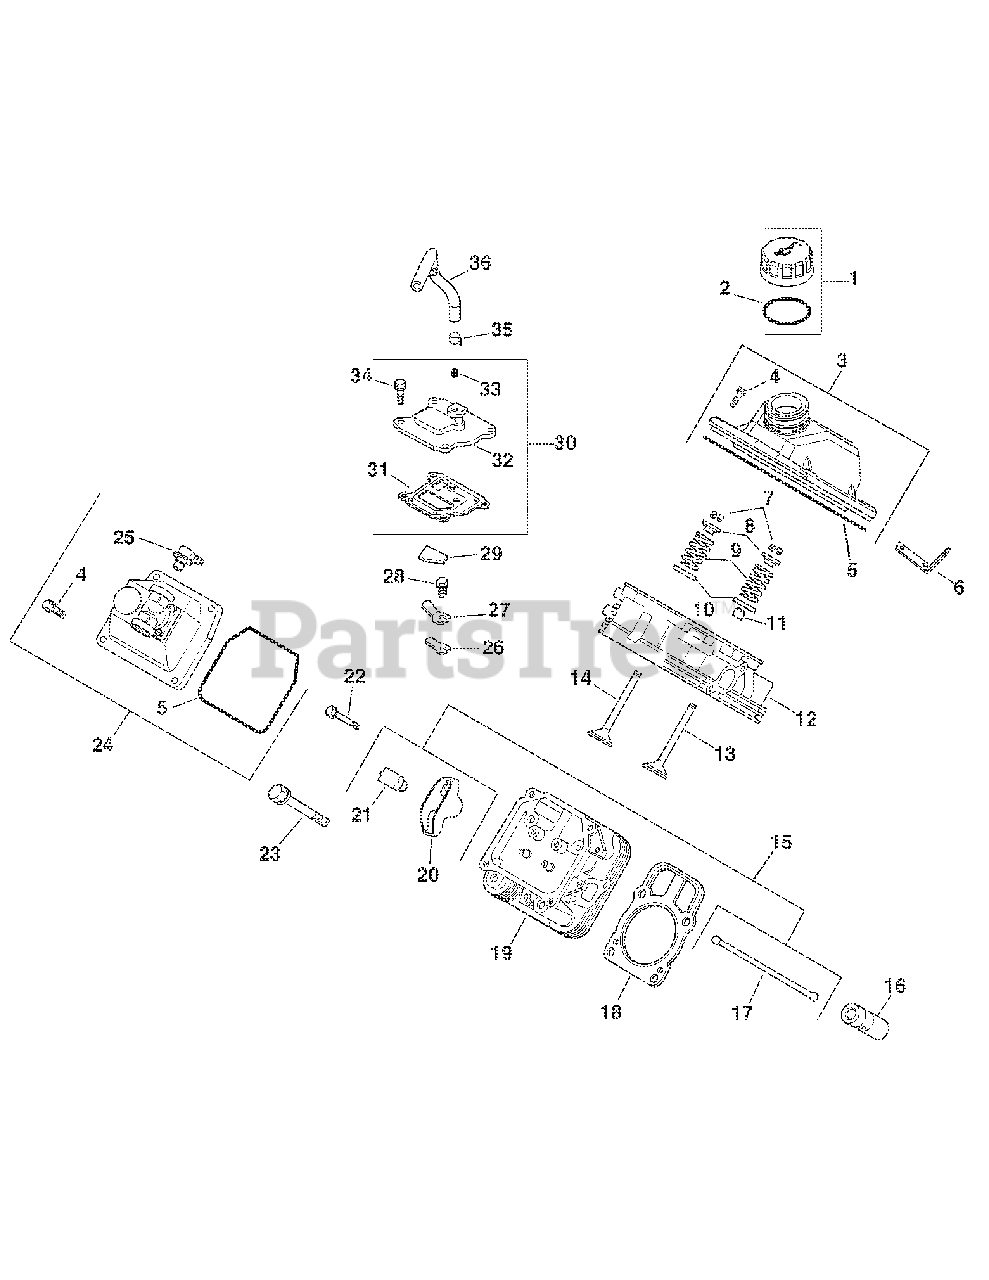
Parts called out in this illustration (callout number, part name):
1	Kit, Oil Fill Cap (Includes 2)
2	O-Ring, dipstick
3	Kit, oil fill rocker cover (Includes 2)
4	Screw, hex. Flange M6x1.0x30 (4)
5	O-Ring, valve cover
6	Strap, lifting (2)
7	Kit, retainer (2)
8	Cap, valve spring (2)
9	Spring, valve (2)
10	Retainer, spring (2)
11	Seal, valve stem
12	Head assembly, #1
13	Valve, intake (Std.)
14	Valve, exhaust (Std.)
15	Kit, valve train (Includes 15, 18, 19)
16	Lifter, valve (4)
17	Rod, push (2)
18	Kit, cylinder head gasket (Includes head mounting hardware)
19	Head assembly #2 cylinder
20	Arm, rocker (2)
21	Pivot, rocker arm (2)
22	Screw, hex. Flange M6x1.0x34 (2)
23	Screw, Flange, M10x1.5x90
24	Kit, fuel pump (Includes 2, 3, 25)
25	Fitting, 90° (2)
26	Reed, breather
27	Retainer, breather reed
28	Screw, hex.flange M5x0.8x10
29	Filter, breather
30	Kit, breathe (Includes
31	Gasket, breather
32	Cover, breather
33	Plug, cast pie
34	Screw, hex. Flange M6x1.0x20 (4)
35	Clamp, hose
36	Hose, breather
